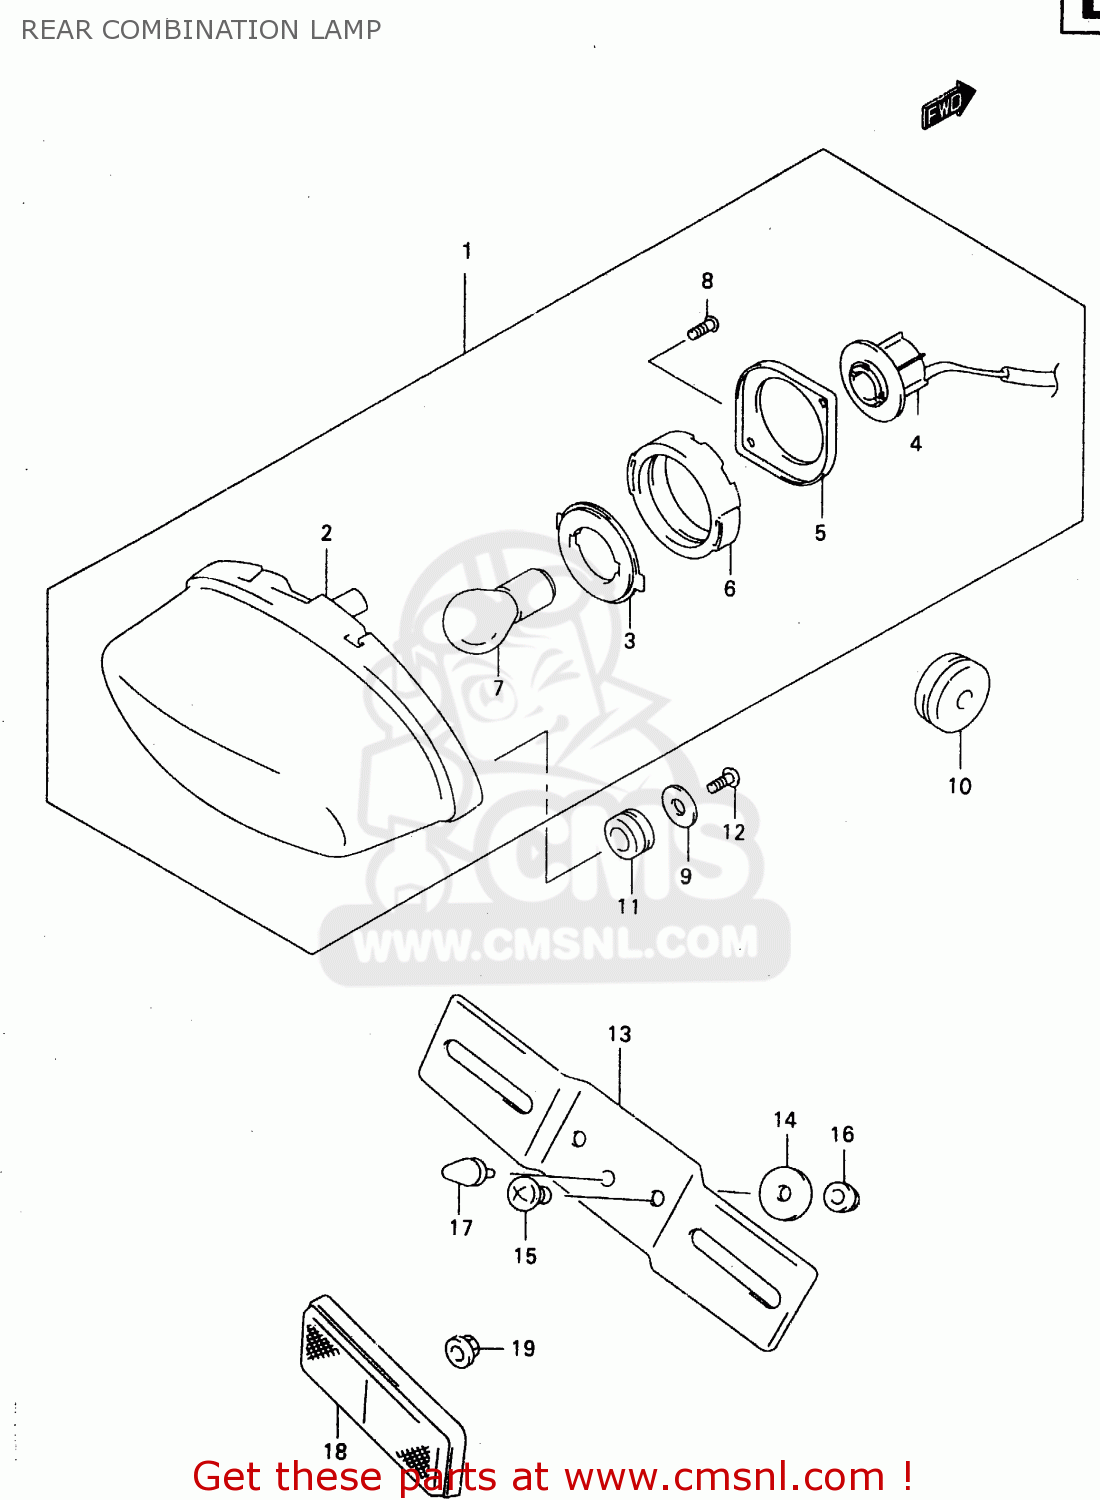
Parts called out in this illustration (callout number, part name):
1	LAMP ASSY,RR COMBINATION
2	LAMP UNIT
3	PLATE NO.1
4	SOCKET & CORD
5	PLATE NO.2
6	CUSHION
7	BULB(12V21/5W)
8	SCREW
9	WASHER(5.5X20X1.2)
10	GROMMET
11	CUSHION
12	SCREW
13	PLATE,RR LICENSE
14	WASHER(6.5X20X1.6)
15	SCREW 6X12
16	NUT
17	CUSHION
18	REFLECTOR ASSEMBLY,REAR
19	NUT
